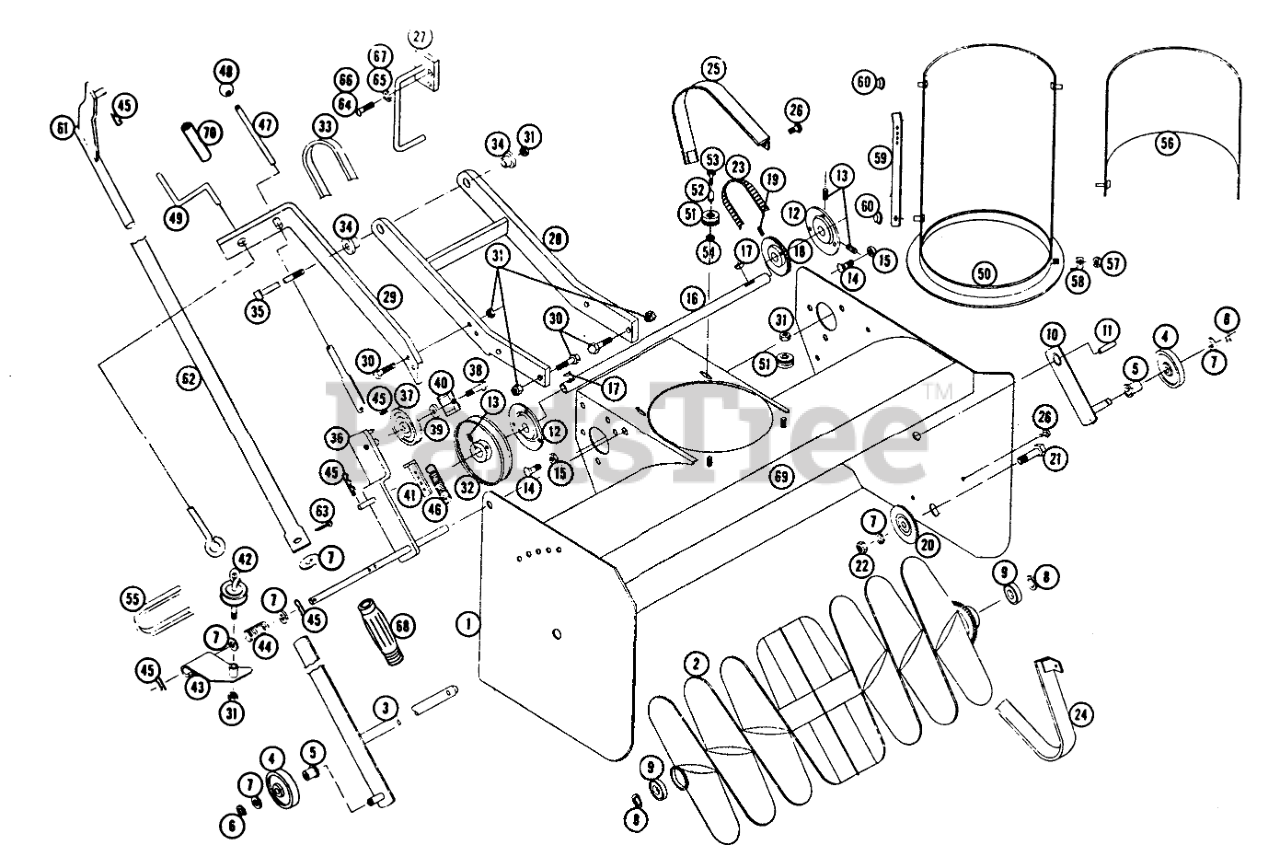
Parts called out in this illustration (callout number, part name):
1	Ass-y Wrapper
2	Auger
3	Ass-y-Auger Shaft (weld)
4	Wheel
5	Bushing
6	Snap Ring .500 Dia. External
7	Washer
8	Washer Auger
9	Ball
10	Ass-y Wheel Support (weld)
11	SPIROL PIN
12	Bearing-Flanged Ball
13	Set Screw 5/16-18 x 5/16
14	Bolt Hex 5/16-18 x 3/4
15	Nut-Nylok
16	Shaft Drive
17	Key
18	SPROCKET
19	Set Screw 1/4-20
20	Idler Sprocket
21	Bolt Hex 1/2-13 x 1 1/2
22	Nut, 1/2-13
23	Chain
24	Ass-y Guard-Inner
25	Guard-Outer
26	SCREW
27	Ass-y. Belt Stop
28	Ass-y Mounting Frame
29	Bracket-Control Support
30	Bolt 3/8-16 x 1
32	Pulley-Drive
33	V-BELT
34	Spacer
35	Bolt-Hex. 3/8-16 x 8 1/2
36	Ass-y Bracket (weld) Idler
37	Pulley
38	Bolt 3/8-16 x 1 1/4 Nylok
39	BUSHING
40	Clip - Belt
41	Link-Spring Tension
42	Ass-y Eye Bolt sheave (weld)
43	Ass-y Bracket & Tube (weld)
44	Spring-Compression
45	Hair Pin
46	SPRING
47	Ass-y-Rod-Clutch (weld)
48	Knob
49	Crank
50	Ass-y Shroud (weld)
51	Roller
52	SPACER
53	Bolt 1/4 20 x 1 1/4
54	Nut 1/4-20
55	Belt-Shroud Drive
56	Deflector
57	Nut-Keps #10-32
58	Clip-Belt
59	ARM R
60	Speed Nut (.187)
61	Lid Rod
62	Tube Lift
63	Cotter Pin 3/16 x 1
64	Screw Rd. Hd. 5/16-24 x 1/2
65	Lockwasher
66	Screw Rd. Hd. 3/8-16 x 1/2
67	Lockwasher
68	Grip
69	Decal
70	Tube-Handle Grip
